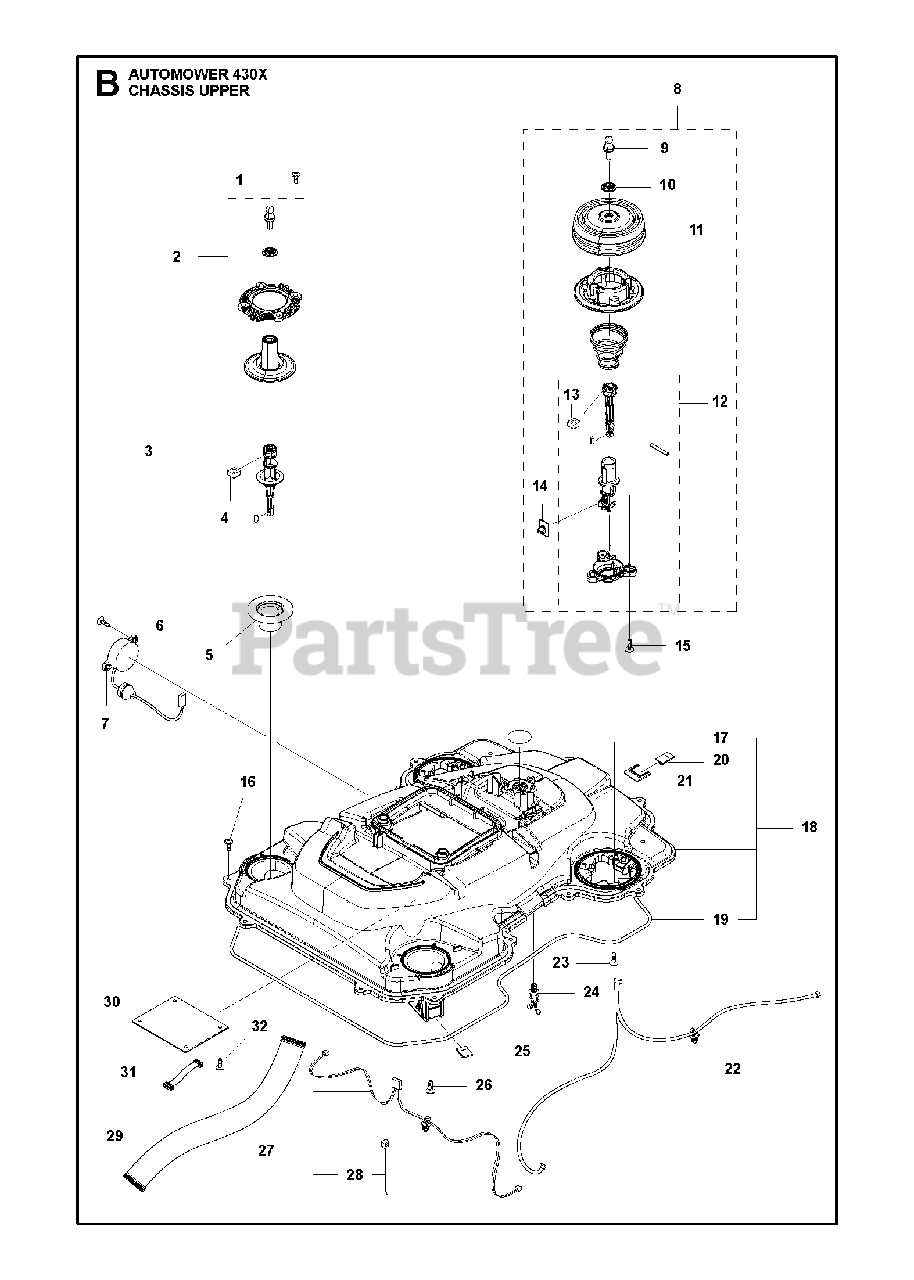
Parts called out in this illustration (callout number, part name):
1	SCREW ITXPANT
2	JOYSTICK KIT REAR
3	JOYSTICK KIT REAR
4	NUT
5	MOVEMENT LIMITER
6	SCREW 14MM
7	BUZZER ASSY
8	JOYSTICK KIT
9	STUD SNAPLOC
10	WASHER JOYSTICK
11	BELLOWS LIFT-COLLISION
12	JOYSTICK KIT
13	NUT
14	PRINTED CIRCUIT ASSY PCBA LIFT
15	SCREW 14MM
16	SCREW ITXPANT
17	KIT AIR FILTER KIT 305 - 10 PC
18	CHASSIS KIT UPPER
19	Sealing Strip
20	PRINTED CIRCUIT ASSY COLLISION
21	CLIP COLLISION BOARD
22	LOOM KIT COLLISION SENSOR
23	SCREW ITXPANT
24	HOLDER TWIST LOCK
25	PRINTED CIRCUIT ASSY COLLISION
26	SCREW 14MM
27	LOOM KIT LIFT SENSOR
28	BAND
29	LOOM MMI
30	PRINTED CIRCUIT ASSY GPS BOARD
31	WIRING ASSY GPS/COMMUNICATION
32	SCREW 14MM
